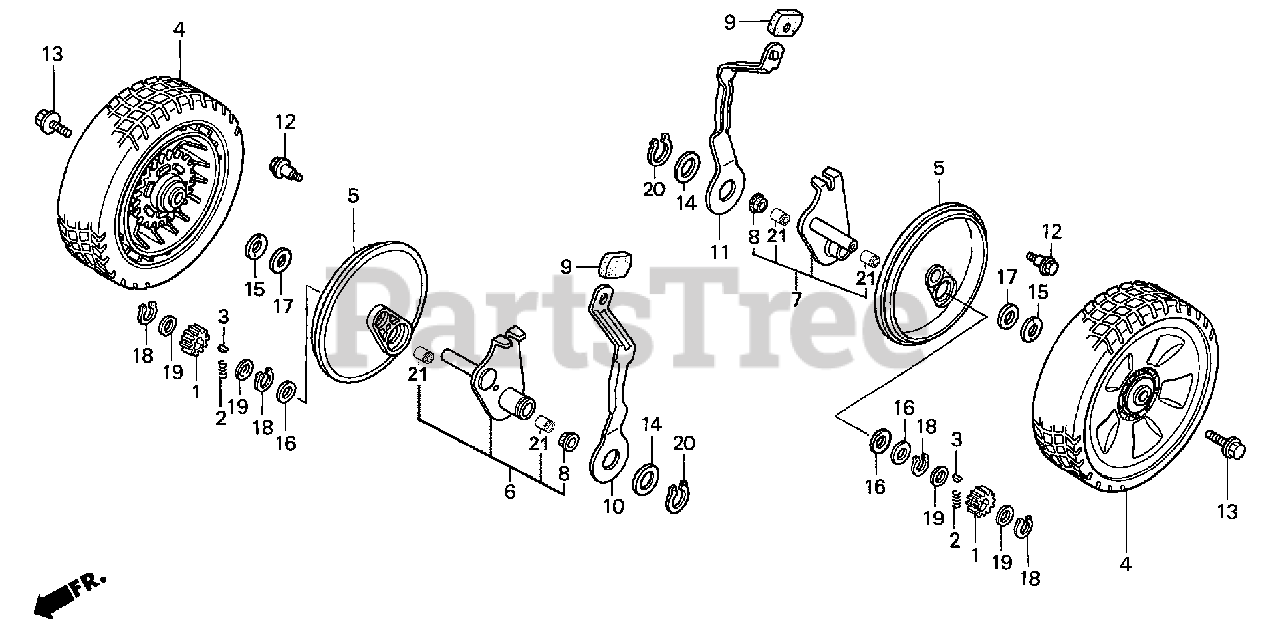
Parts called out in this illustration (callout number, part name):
1	GEAR, PINION (12T)
2	SPRING, RATCHET RETURN
3	KEY, RATCHET
4	WHEEL, RR.
6	ARM, R. RR. ADJUSTING
7	ARM, L. RR. ADJUSTING
8	DUST SEAL (12.7MM)
9	GRIP, ADJUSTER
10	PLATE, R. RR. ADJUSTER
11	PLATE, L. RR. ADJUSTER
12	SCREW, TAPPING (5X12)
13	BOLT, WHEEL
14	WASHER, PLAIN (22MM)
15	WASHER, WHEEL
16	WASHER, THRUST (13MM)
17	WASHER, THRUST (13X27X1)
18	CIRCLIP (OUTER) (12.7MM)
19	COLLAR, PINION GEAR
20	CIRCLIP (OUTER) (22MM)
21	BUSH, DRIVESHAFT
